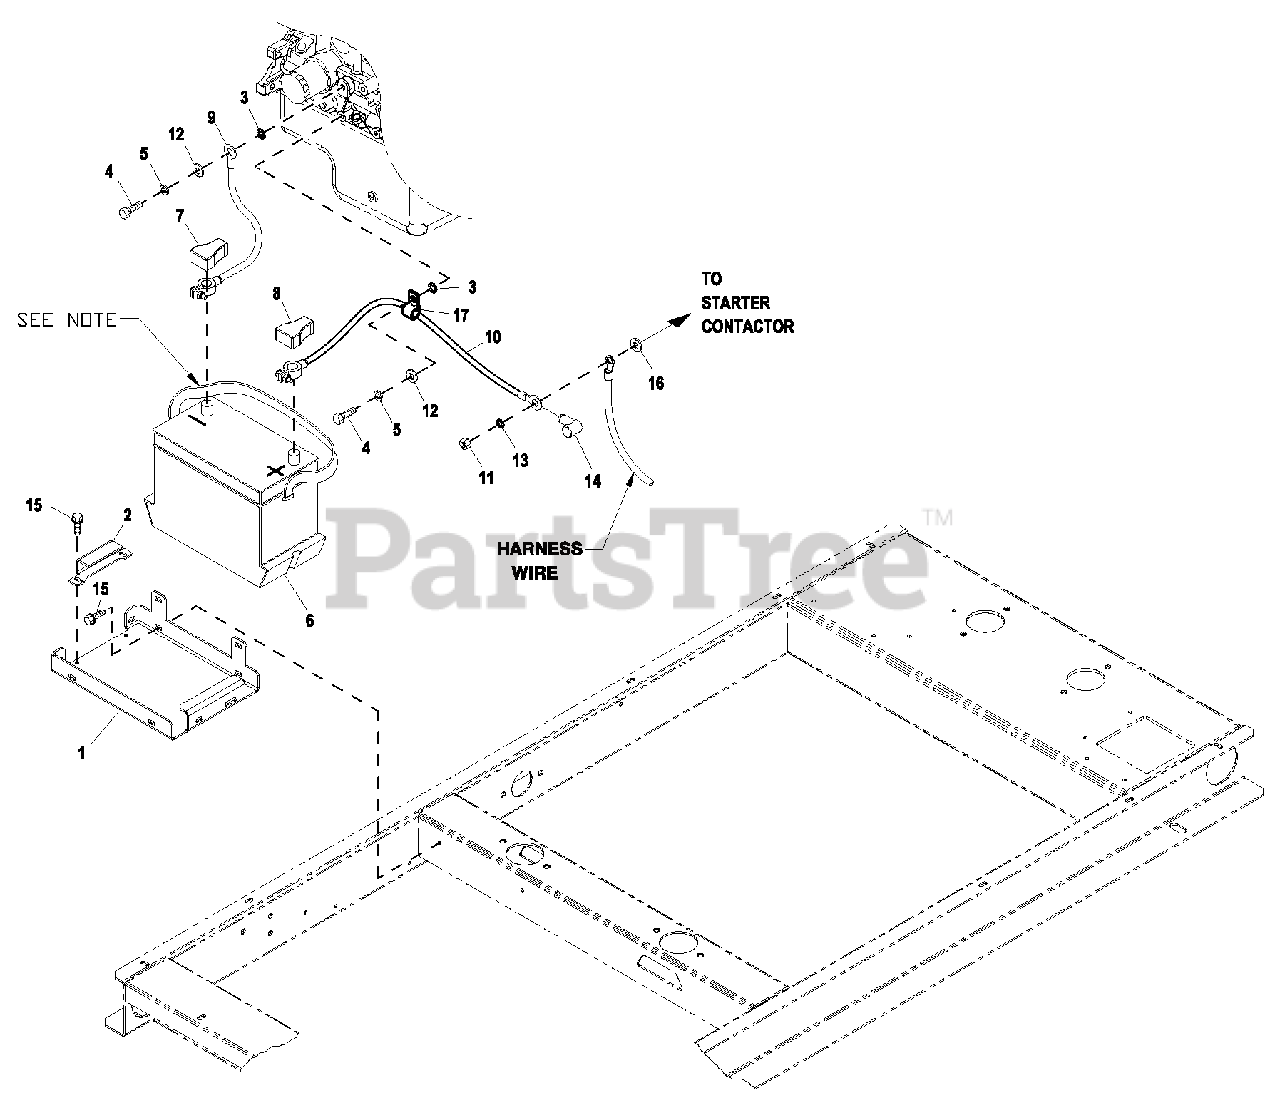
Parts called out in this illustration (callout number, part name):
1	BATTERY TRAY, C1 & C2
2	STRAP BATTERY RETAINMENT
3	WASHER SHAKEPROOF EXT 7/16 ST L
4	SCREW HHC M10-1.5X 25 G10.9
5	WASHER LOCK M10
6	BATTERY 12VDC 75-AH26
7	BATTERY POST COVER RED +
8	BATTERY POST COVER B LK -
9	CAB LE BATTERY B LACK #1 X 30.00
10	CAB LE BATTERY RED #1X21.00
11	NUT HEX M8-1.25 G8 YE LCHR
12	WASHER F LAT 3/8-M10 ZINC
13	WASHER SHAKEPROOF EXT 5/16 ST L
14	BOOT CONTACTOR CAB LES
15	SCREW THF M6-1 X 16 N WA Z/JS
16	WASHER F LAT 5/16-M8ZINC
17	C LAMP ST L/VN L .62X.406Z
